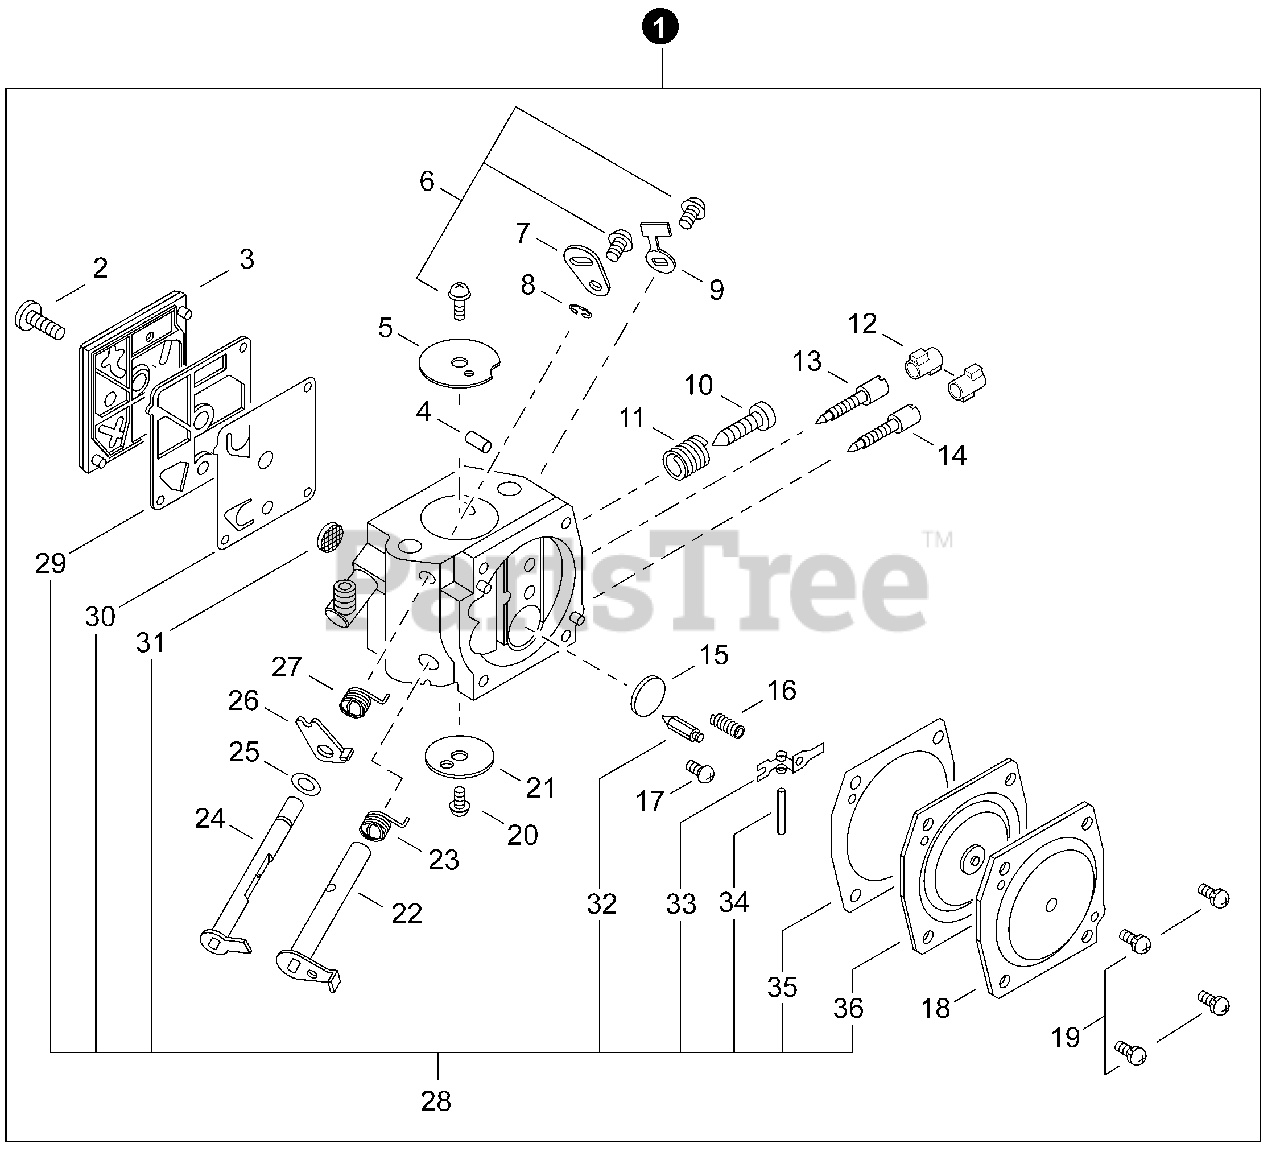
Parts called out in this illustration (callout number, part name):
1	CARBURETOR - HDA-271A
3	COVER, FUEL PUMP
4	PLUG, FRICTION
5	VALVE, CHOKE
7	LEVER, CHOKE
9	STOP, THROTTLE
10	SCREW, IDLE ADJUST
12	CAP, LIMITER
13	NEEDLE, HIGH SPEED
14	NEEDLE, MIXTURE
15	PLUG, WELCH
17	SCREW, METERING LEVER PIN
18	COVER, METERING DIAPHRAGM
21	VALVE, THROTTLE
22	SHAFT ASSY, THROTTLE
23	SPRING, THROTTLE RETURN
24	SHAFT ASSY, CHOKE
26	LEVER, FAST IDLE
27	SPRING, CHOKE RETURN
28	REPAIR KIT
29	GASKET, FUEL PUMP
30	DIAPHRAGM, FUEL PUMP
31	SCREEN, FUEL INLET
32	VALVE, INLET NEEDLE
33	LEVER, METERING
34	PIN, METERING LEVER
35	GASKET, METERING DIAPHRAGM
36	DIAPHRAGM, METERING
